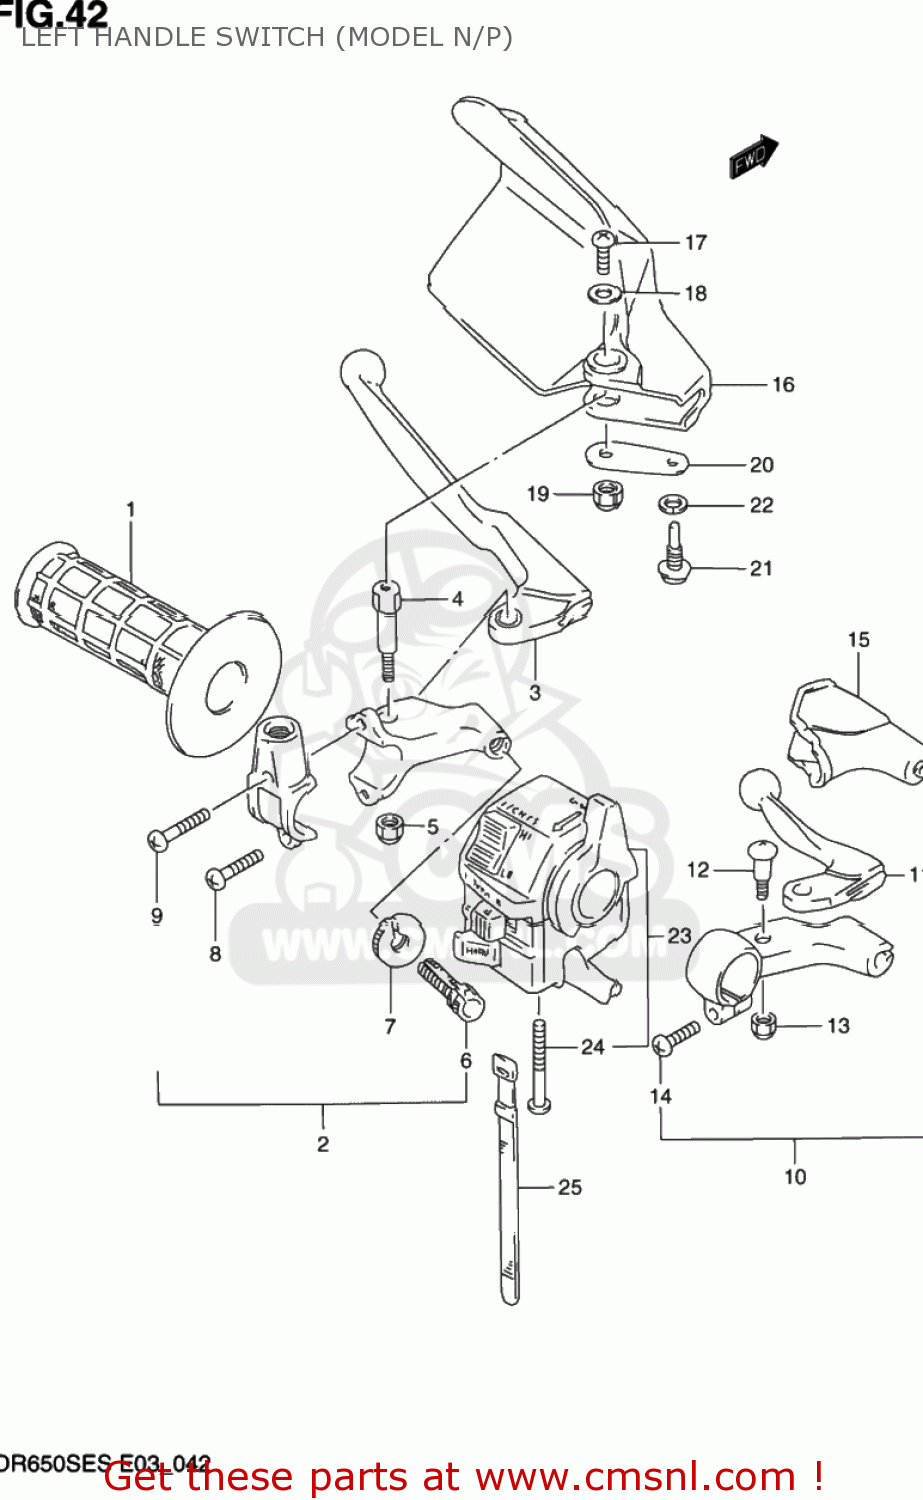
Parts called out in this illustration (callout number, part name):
1	GRIP,L
2	LEVER ASSY,CLUTCH
3	LEVER,CLUTCH
4	BOLT,LEVER SET
5	NUT 6MM
6	ADJUSTER,CABLE
7	NUT,LOCK
8	SCREW
9	SCREW(5X22)
10	LEVER ASSEMBLY,DECOMPRESSION
11	LEVER,DECOMP
12	BOLT,LEVER PIVOT
13	NUT
14	SCREW
15	COVER,DECOMP LEVER DUST
16	COVER,KNUCKLE,L
17	SCREW(5X10)
18	WASHER (5.5X16X1.2)
19	NUT 6MM
20	PLATE,KNUCKLE COVER,L LWR
21	SCREW
22	WASHER,LOCK
23	SWITCH ASSEMBLY,HANDLE,LEFT
24	SCREW, 5X45
25	CLAMP(L:120)
